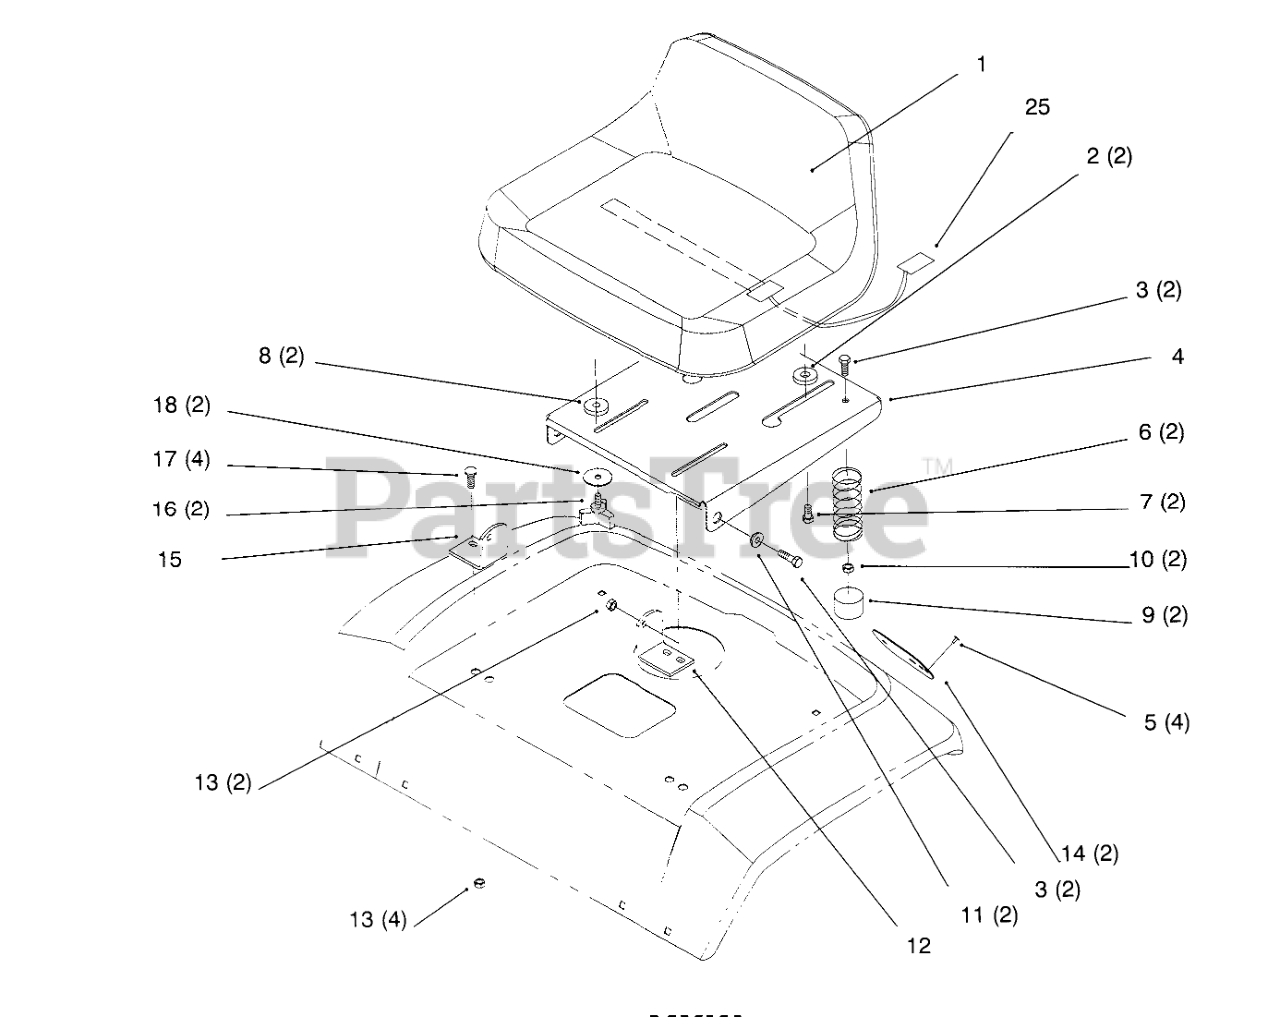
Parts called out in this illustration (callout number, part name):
1	Seat (Only On: 72042,72043)
1	Seat (Only On: 72062,72063,72103)
2	SPACER-NYLON
3	SCREW-HH
4	SUPPORT - SEAT (BLACK)
5	RIVET-BLIND
6	SPRING-COMPRESSION
7	BOLT-SHOULDER
8	SPACER-NYLON
9	CAP-PROTECTOR
10	NUT-LOCK, NI
11	BUSHING
12	BRACKET-PIVOT, LH
13	NUT-LOCK, NI
14	REFLECTOR-STICK ON
15	BRACKET-PIVOT, RH
17	BOLT-CARR
18	WASHER-PIVOT
25	SWITCH-SEAT
